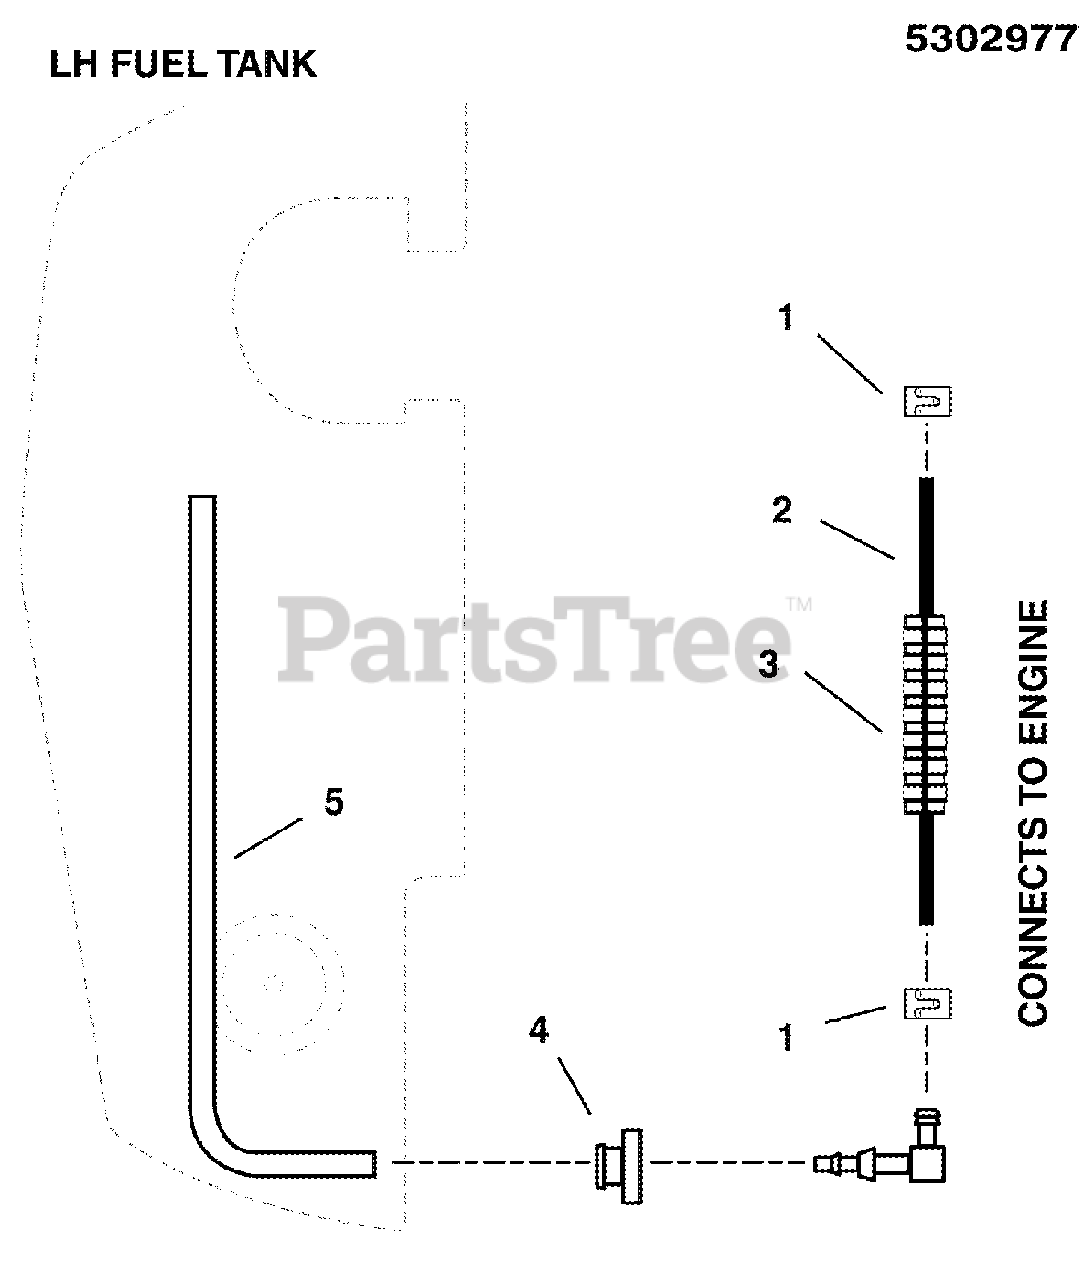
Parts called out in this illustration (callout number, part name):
1	CLAMP, HOSE, EXTERNAL, 1/2 - RED
3	WIRE LOOM, 1/2 ID X 5 IN
4	BUSHING-FUEL TANK RED RUBBER (SV)
5	HOSE, 1/4" FUEL, 25.00"
